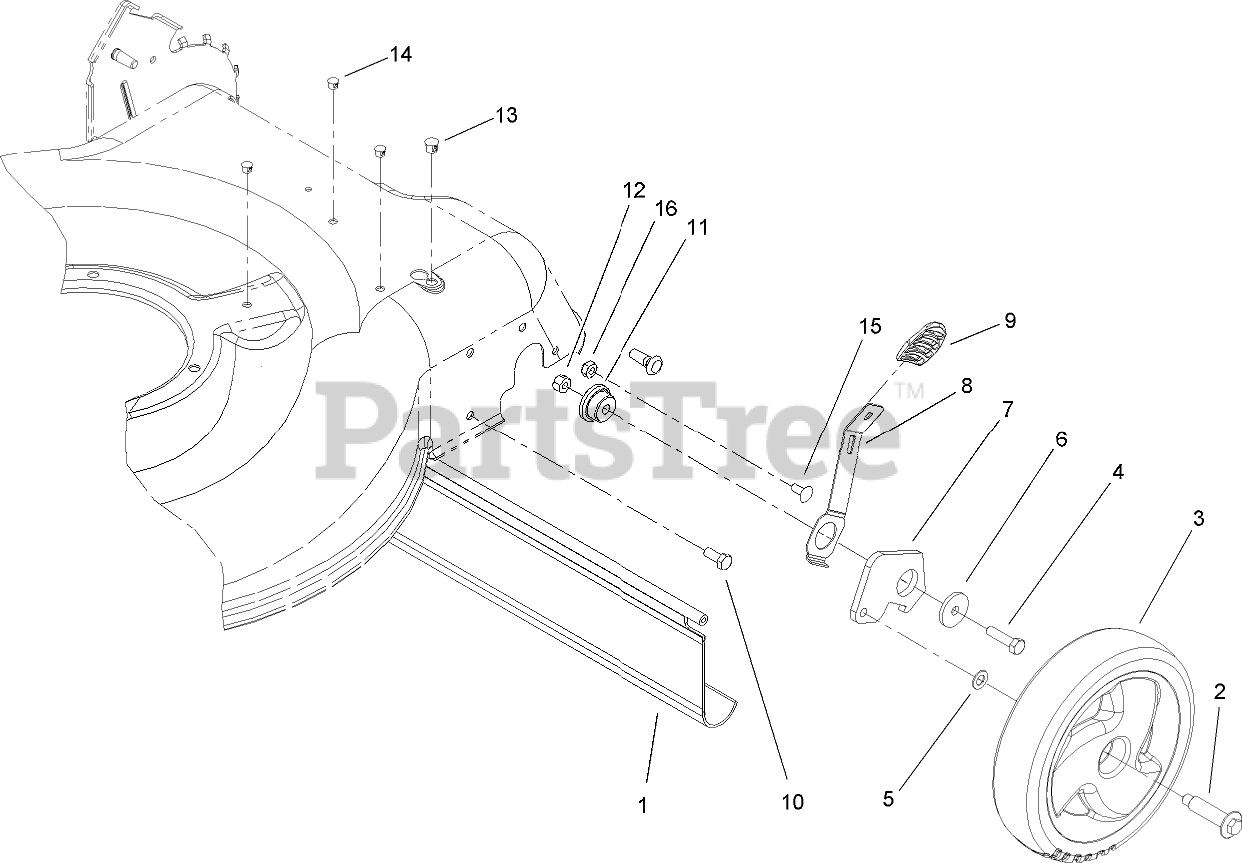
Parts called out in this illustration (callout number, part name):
1	Shield-Trailing
2	BOLT-SHOULDER
3	WHEEL ASM (59505)
4	SCREW-HH
5	WASHER
6	Washer-Flat
7	Arm-Pivot, Rear (LH)
8	Arm-Spring
9	Knob-Lever, HOC
10	SCREW-HH
11	Bushing-Mount, HOC
12	NUT-LOCK, NI
13	Plug-Dome
14	Plug-Dome
15	SCREW-CARR
16	NUT-LOCK, NI
